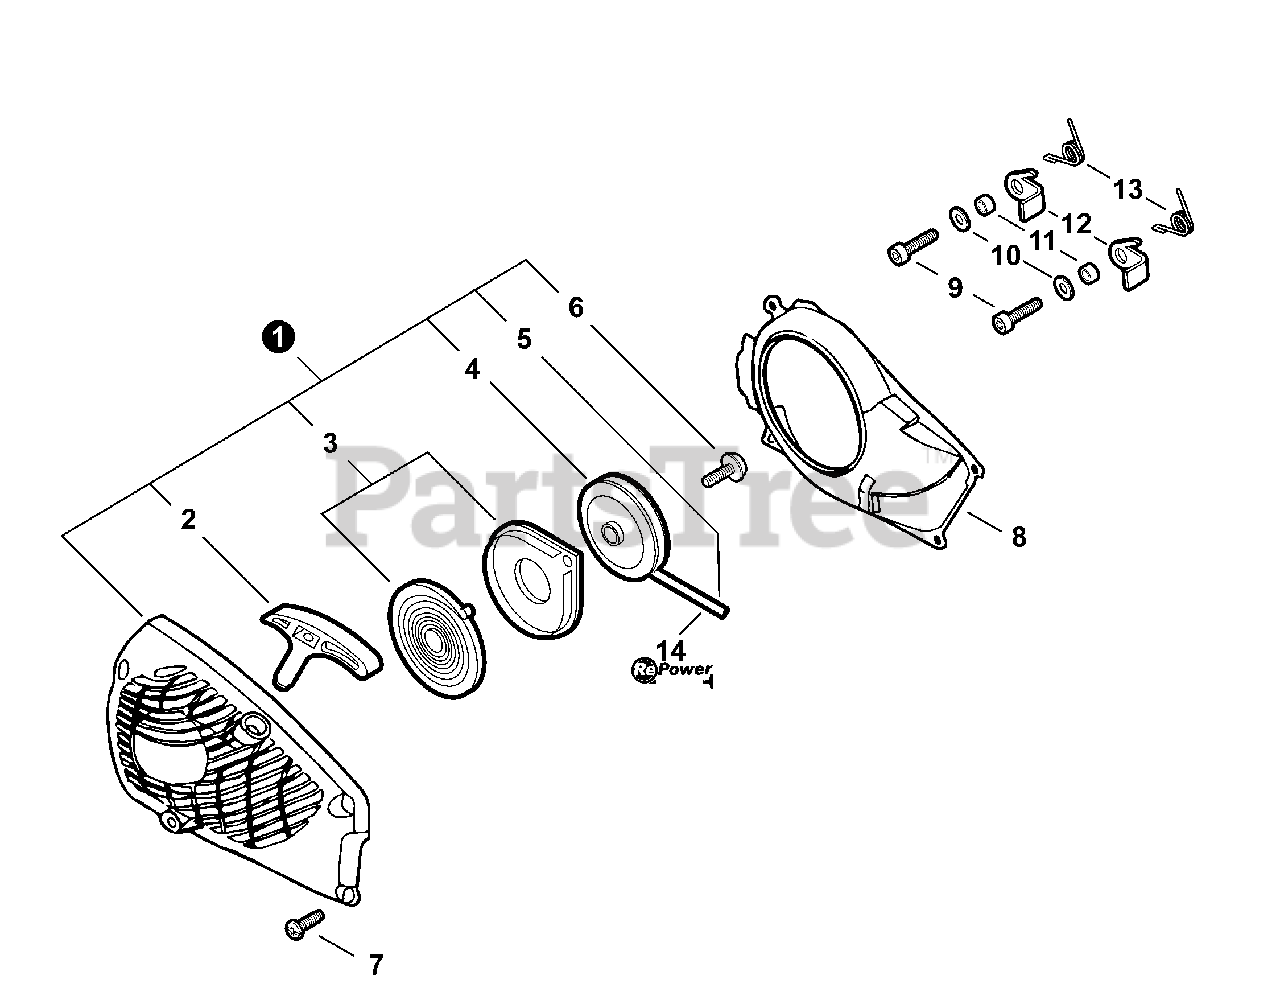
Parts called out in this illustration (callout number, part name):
1	STARTER ASSY, RECOIL - ORANGE
2	GRIP, STARTER
3	SPRING SET, RECOIL
4	REEL, ROPE
5	ROPE, STARTER
8	COVER, FAN
9	BOLT 5×14
10	WASHER 5.5×12×0.8
11	SPACER 5.2×8×2.1
13	SPRING, TORSION
14	ROPE, STARTER - REPOWER BULK 3
